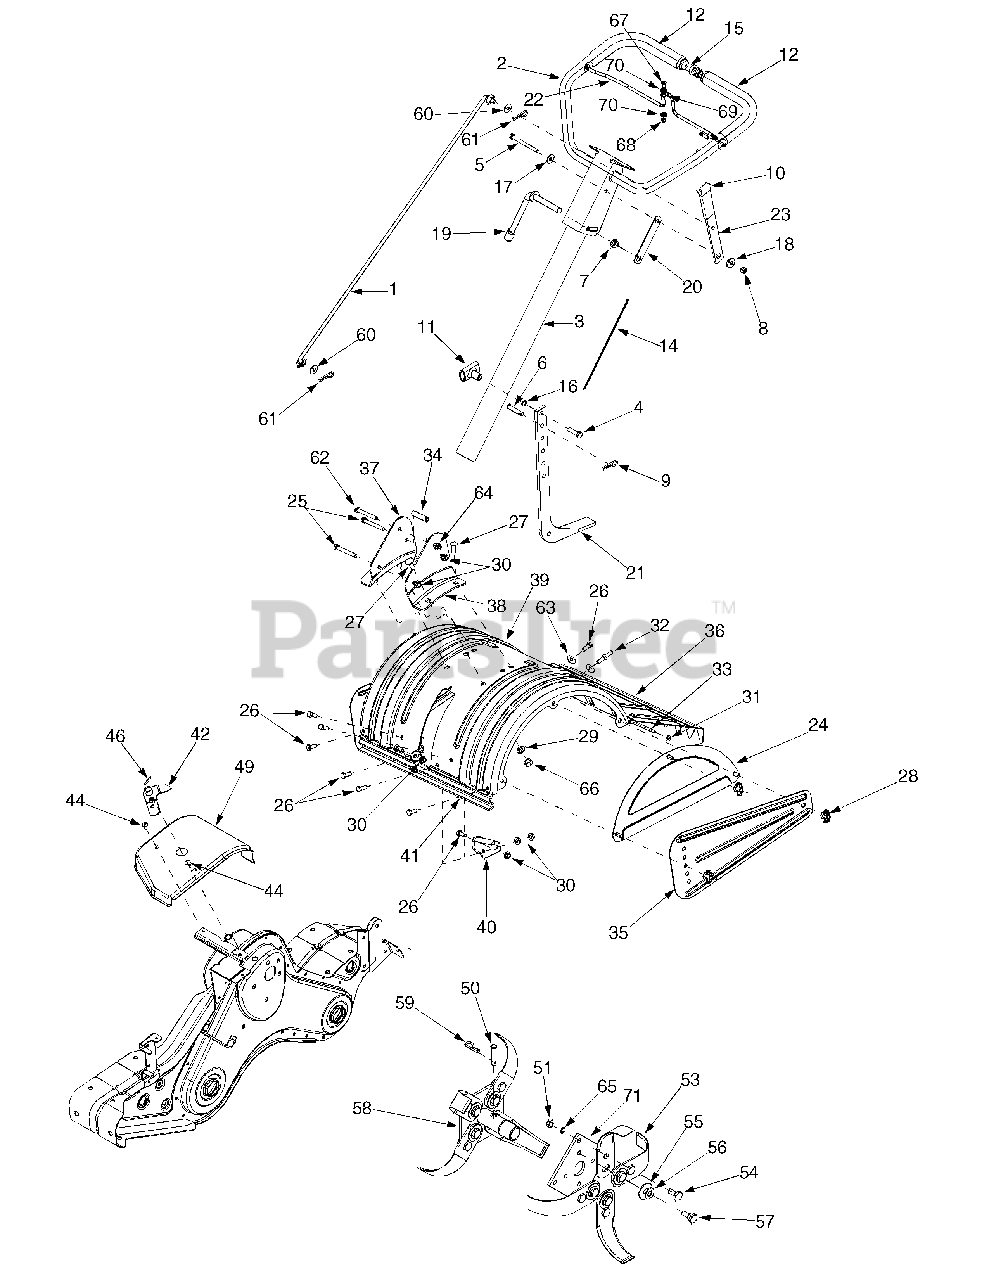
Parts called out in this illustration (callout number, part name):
1	Shift Rod
4	Hex Screw 3/8-16 x 1.25
5	Hex Screw 5/16-18 x 3.25
6	Clevis Pin 3/8-1.62
7	Flange Lock Nut 3/8-24
8	Hex Lock Nut 5/16-18
9	Cotter Pin
11	T-Knob
12	Foam Grip
14	Cable Tie
16	Flat Washer 3/8 ID x .620 OD
17	Bell Washer .340 ID x .872 OD
18	Shoulder Spacer
19	Handle Adjustment Crank
20	Hex Nut Retainer Bracket
21	Depth Stake
22	Bail Clutch
25	Hex Cap Screw 5/16-18 x 2.75
26	Hex Cap Screw 5/16-18 x .750
27	Carriage Bolt 3/8-16 x 1.0
28	Wing Nut
29	Lock Washer 3/8
30	Flange Nut 5/16-18
31	Cap Nut
32	Hex Screw 5/16-18 x .75"
34	Spacer .322 x .625 x 2.0
40	Tine Shield Bracket
41	Shoulder Spacer Bracket
42	Shift Crank Assembly
44	Screw 1/4-14 x .625
46	Spiral Pin 3/16 x 1.0
51	Hex Nut 3/8-24
53	13" Articulating Tine
54	Shoulder Bolt
55	Flat Washer .51" ID x 1.50" OD
56	Bell Washer .515" ID x 1.14" OD
57	Shoulder Bolt
58	Tine Adapter Assembly 18"
59	Internal Cotter Pin
60	Rubber Washer
61	Cotter Pin
62	Hex Screw 3/8-16 x 2.75"
63	Flat Washer
64	Flange Nut 3/8-16
65	Lock Washer
66	Hex Nut 3/8-16
67	Truss Screw 1/4-20 x .65
68	Hex Lock Nut 1/4-20
69	Battery Hose Clamp 5/16
70	Flat Washer .260 ID x .720 OD
71	Tine Adapter Plate
